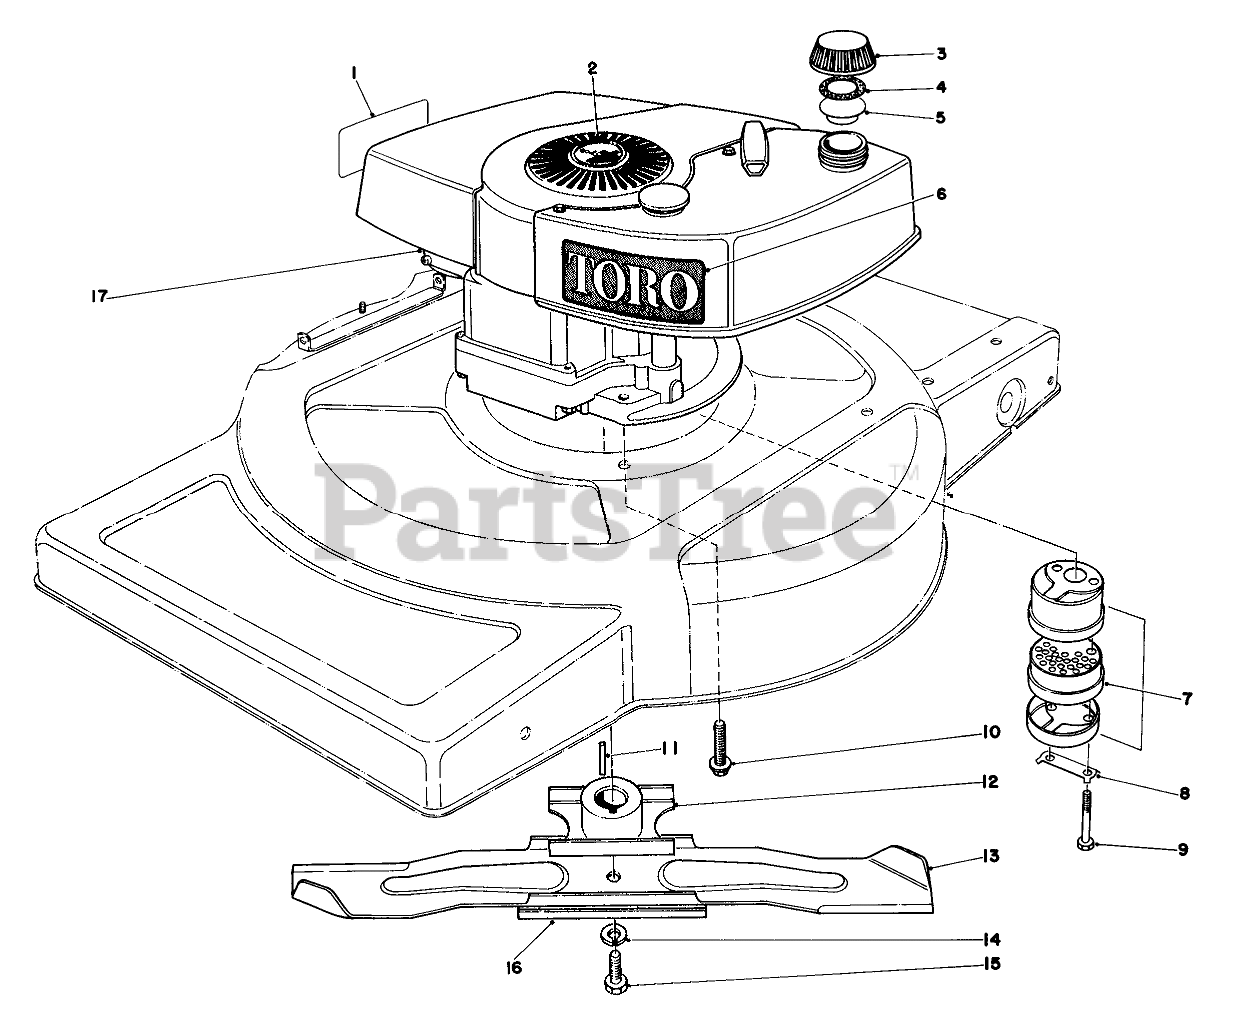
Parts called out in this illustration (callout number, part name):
1	Decal-Maintenan
2	PLUG BUTTON
3	Gas Cap (Incl. Ref. #4 & 5 &)
4	GASKET
5	GAS CAP BAFFLE
6	Decal Tow
7	Muffler Assembly (Incl. Ref. #8 & 9)
8	CLIP - LOCKING
9	SCREW-HH
10	SCREW-HWHTF
11	KEY-SQUARE
12	BLADE RETAINER WA
13	Blade
14	WASHER-LOCK
15	SPECIAL SCREW
16	Stiffener-Blade
17	Engine
